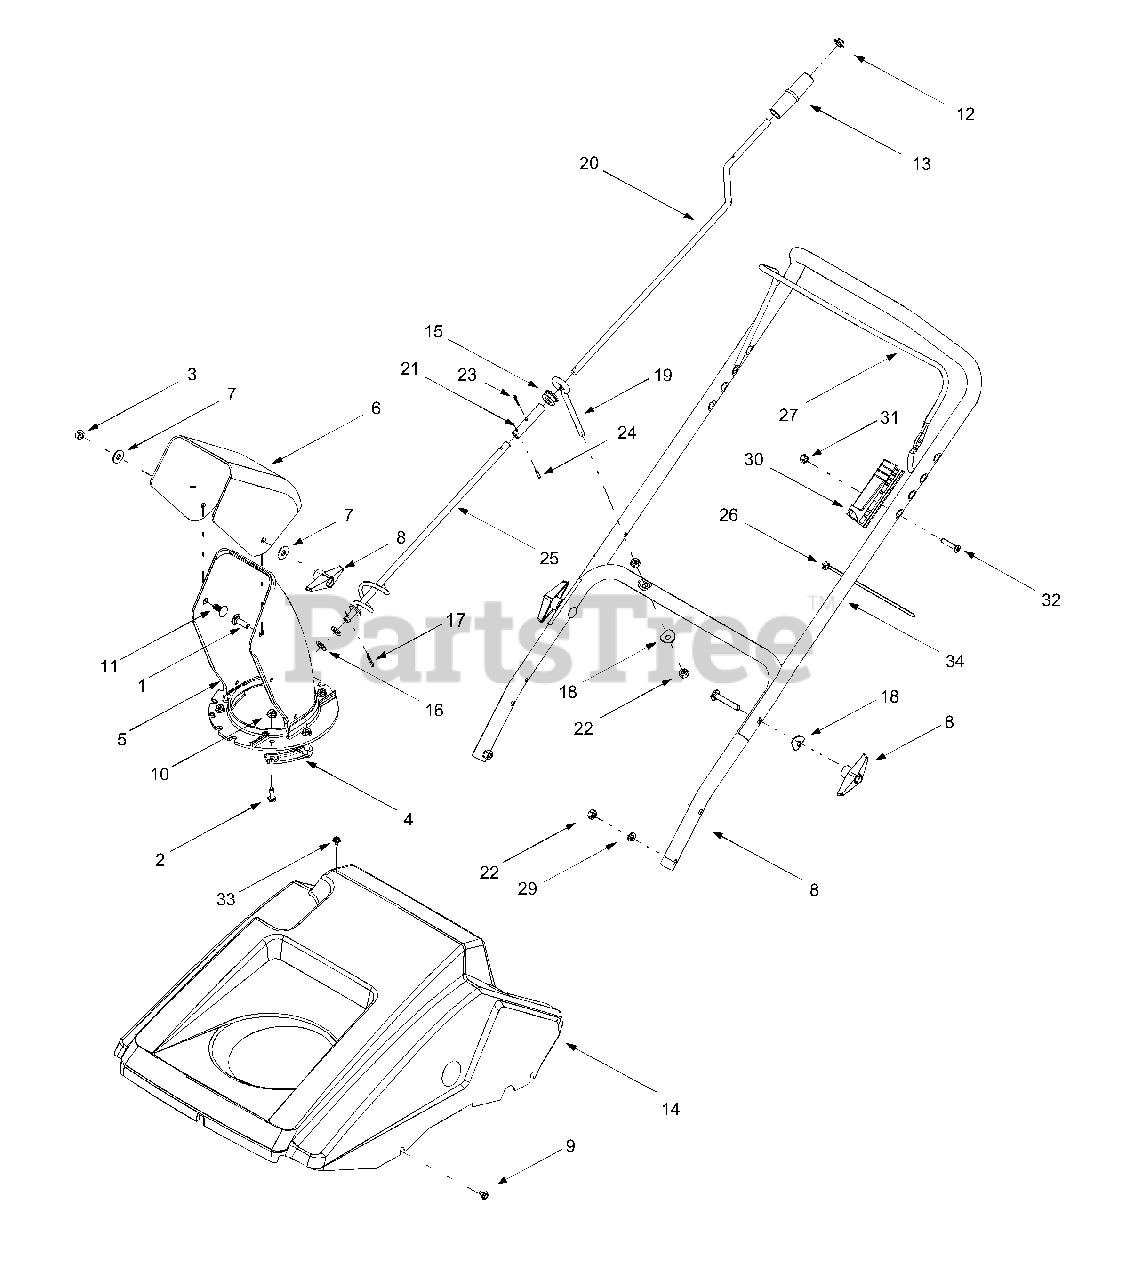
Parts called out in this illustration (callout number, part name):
1	Splined Carriage Screw, 5/16-18 x 1.0
2	Hex Cap Screw, 1/4-20 x.75
3	Hex Lock Nut, 5/16-18
4	Chute Flange Keeper
5	Lower Chute, 5.0
6	Upper Chute, 5.0
7	Washer, .349 x .879 x .063
8	Wingnut Knob, 5/16-18
9	Screw, #10-16 x .375
10	Hex Flange Lock Nut, 1/4-20
11	Carriage Bolt, 5/16-18 x .75
12	Push Cap, 3/8
13	Knob, 1.0 x 3.2
14	Shroud, Gray
15	Rubber Grommet, .44 x .94 x .50
16	Flat Washer, .375 x .738 x .063
17	Internal Cotter Pin, .072 x 1.12
18	Saddle Washer, .320 x .93
19	Eyebolt, .70
20	Upper Chute Crank
21	Spacer, .382 x .50 x 1.12
22	Hex Nut, 5/16-18
23	Cotter Pin, 3/32 x .75
24	Rolled Pin, 1/8 x .63
25	Chute Crank Assembly
26	Cable Tie
28	Lower Handle
29	Lock Washer, 5/16
30	Control (Cable) Housing
31	Nylon Hex Lock Nut, 1/4-20
32	Machine Screw, 1/4-20 x 1.31
33	Screw, #10-16 x .625
